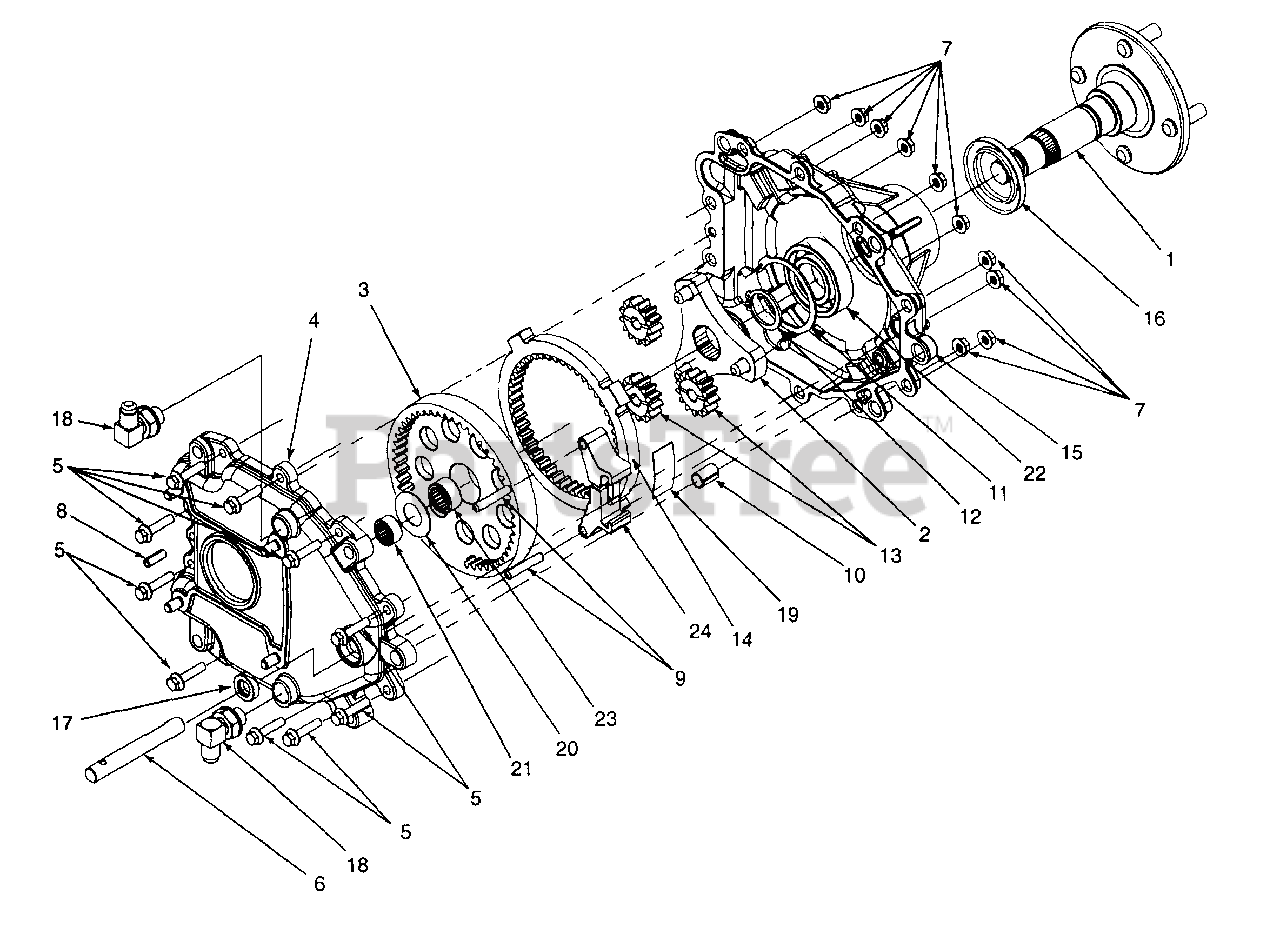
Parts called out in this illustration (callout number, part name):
1	Axle Assembly
2	Carrier Assembly, Output
3	Gear Assembly, 51T Internal & 20T
4	Housing Ass'y
5	Hex Washer Screw 1/4-20 x 1-1/8
6	Brake Shaft
7	Hex Flange Lock Nut 1/4-20
9	Dowel Pin
10	Bushing
11	Inverted Retaining Ring
12	Snap Ring
13	Spur Gear 13T
14	Ring Gear 46T
15	Axle Outer Housing
16	Oil Seal
18	Elbow Fitting
19	Brake Shoe Spring
20	Shim Washer .76 x 1.5 x .030
21	Needle Bearing
22	Ball Bearing
23	Needle Bearing
24	Shoe Brake
